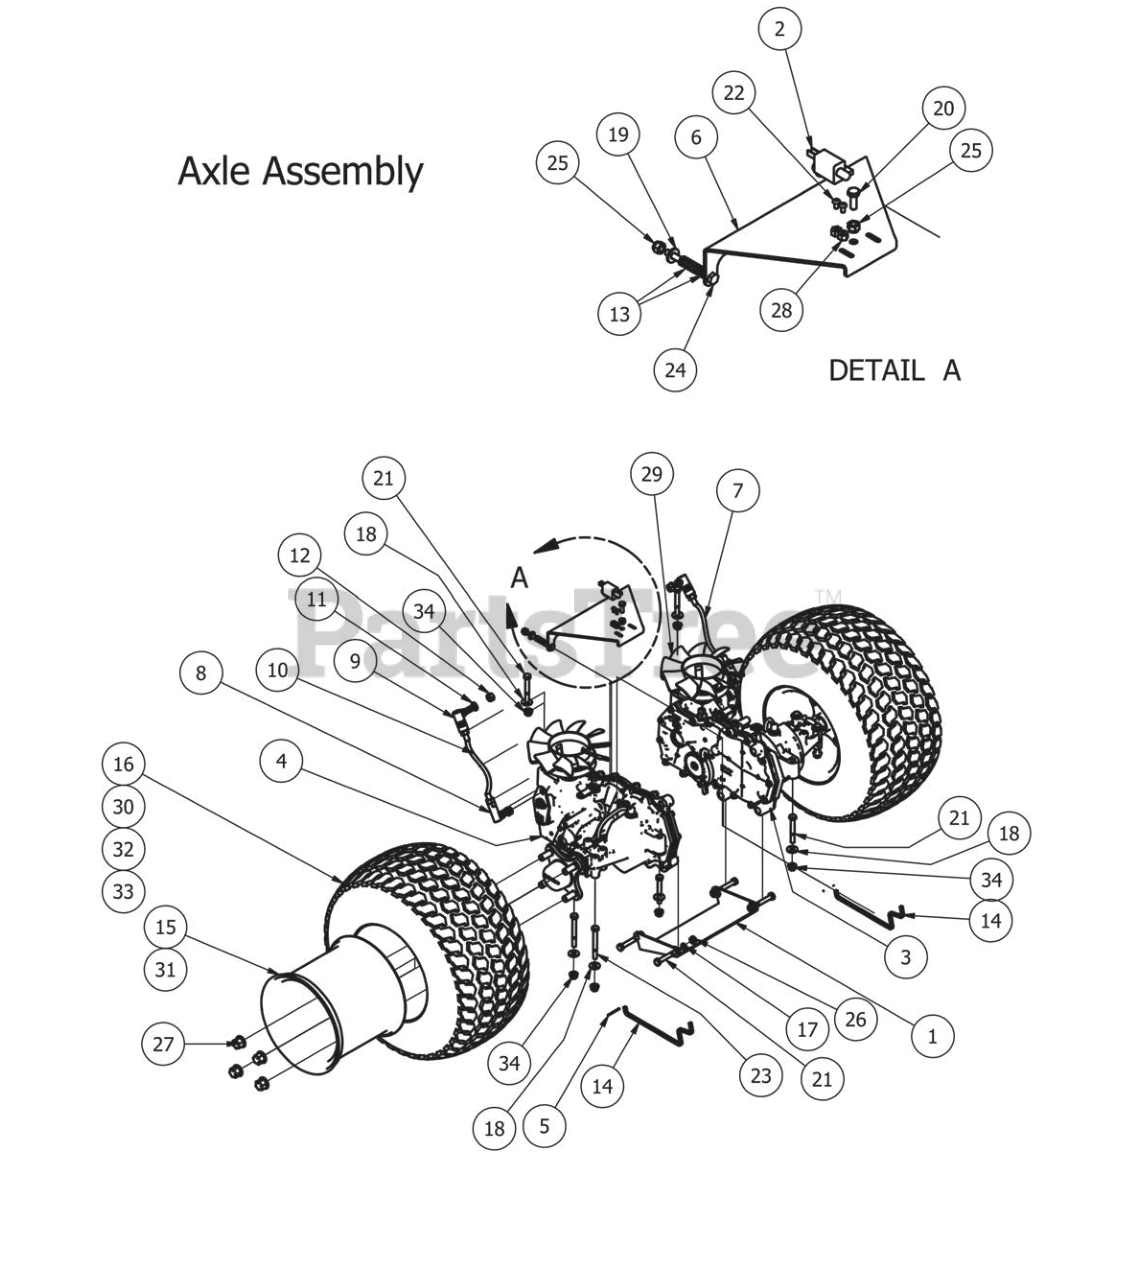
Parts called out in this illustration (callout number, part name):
1	MZ Transaxle Support (Lower)
2	Safety Switch
3	EZT - Right MZ Models
4	EZT-Left MZ Models
5	Cotter Pin-Brake bar on Mz
6	MZ Brake Lock Bracket
7	Steering linkage for Mz Left
8	3/8-24 Ball Joint
9	Quick Release Ball Joint
10	Steering linkage for Mz right
11	3/8" Lock Washer
12	3/8" Fine Threaded Jam Nut
13	Brake Spring
14	MZ Brake Release Bar
15	Rear rim for a 48 & 54"
16	18 x 9.50 8 Tire Only MZ 48 &54" Deck only
17	5/16" Lock Washer
18	5/16" Flat Washer
19	1/4" Flat Washer
20	1/4" x 3/4" Hex Bolt
21	5/16" x 2 1/2" Bolt
22	10-24 X 5/8 BS C/S 18-8 SS
23	5/16" x 3" Hex Bolt
24	1/4-20 x2-1/2 Gr2 hex C/s zinc
25	1/4" Nylock Nut
27	Acorn Lug Nut
28	10-24 Nylon Insert Locknut
29	MZ Fan & Pulley Kit
30	42" MZ 18x 7.50-8 tire only
31	Rear rim only 42" MZ
32	18x9.50-8 48 & 54" Deck Tire and Wheel Assembly
33	18x8.50-8/8" 42" Deck Tire and Wheel Assembly
34	5/16" Nylon Flange Nut
